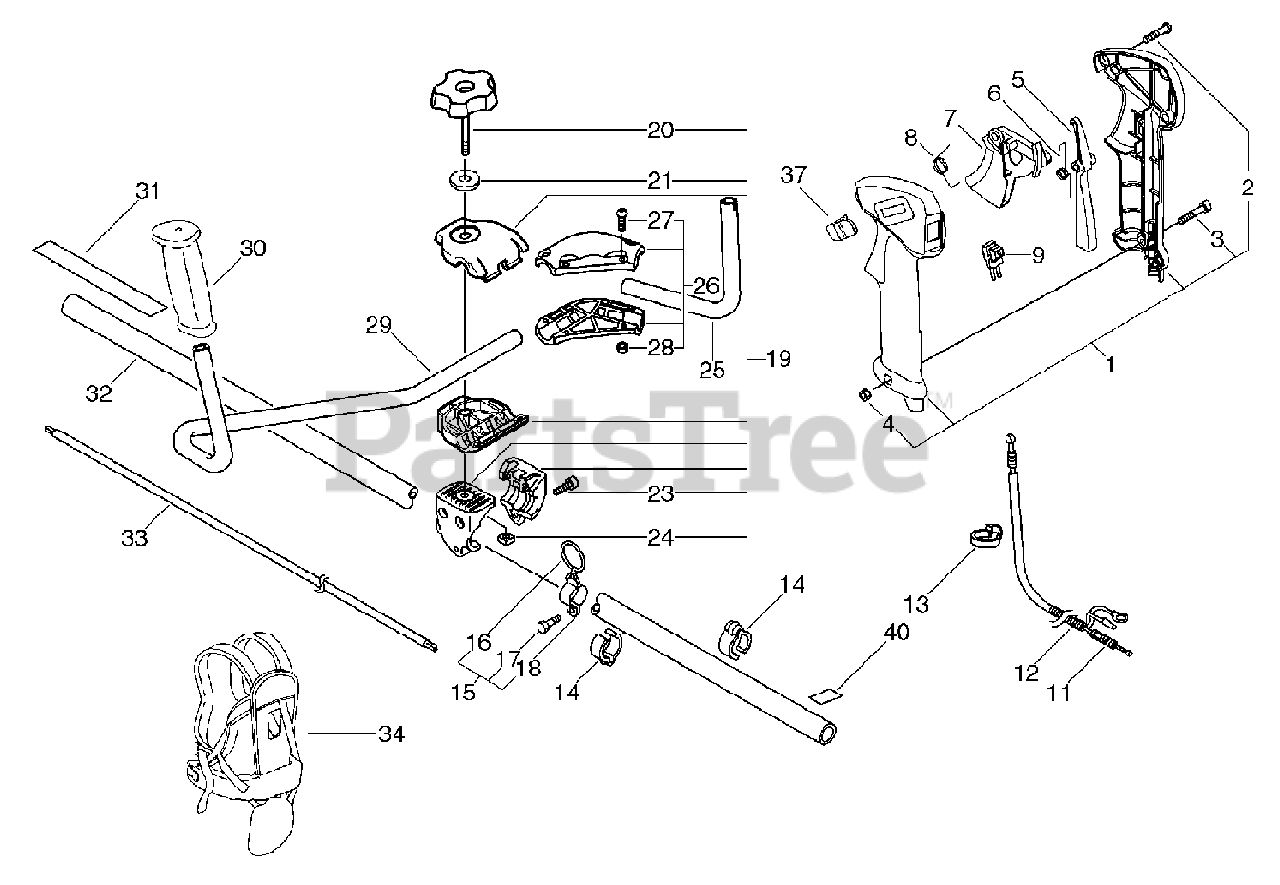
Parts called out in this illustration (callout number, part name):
1	CONTROL HANDLE KIT
1	CONTROL HANDLE ASSY
1	FRONT HANDLE GRIP ASSY
1	GRIP ASSY, THROTTLE
2	SCREW 3×25
2	SCREW 4×16
3	SCREW 5×30
4	NUT M5
5	LOCKOUT, THROTTLE
6	SPRING, TORSION
7	TRIGGER, THROTTLE
8	SPRING, TORSION
9	IGNITION SWITCH ASSY
11	CABLE, THROTTLE
12	PIPE
13	CLIP
14	CLIP 28 MM
15	HANGER KIT
16	RING, HARNESS
17	BOLT 5×12
18	HANGER, HARNESS
19	HANDLE BRACKET KIT
19	BRACKET ASSY, HANDLE
20	BOLT 8×55
20	KNOB, SCREW M8
21	WASHER 8
22	BOLT 5×20
23	BOLT 5×30
24	NUT 8×1.25
25	HANDLEBAR, RIGHT
26	BRACKET ASSY, HANDLE
27	BOLT 5×20
28	NUT M5
29	HANDLEBAR, LEFT
30	GRIP, HANDLE
31	LABEL - CAUTION
31	LABEL, CAUTION - ISO
32	MAIN PIPE ASSY
33	DRIVESHAFT
34	HARNESS ASSY, SHOULDER
34	HARNESS, SHOULDER
35	LABEL, STOP
40	LABEL - ALIGNMENT
